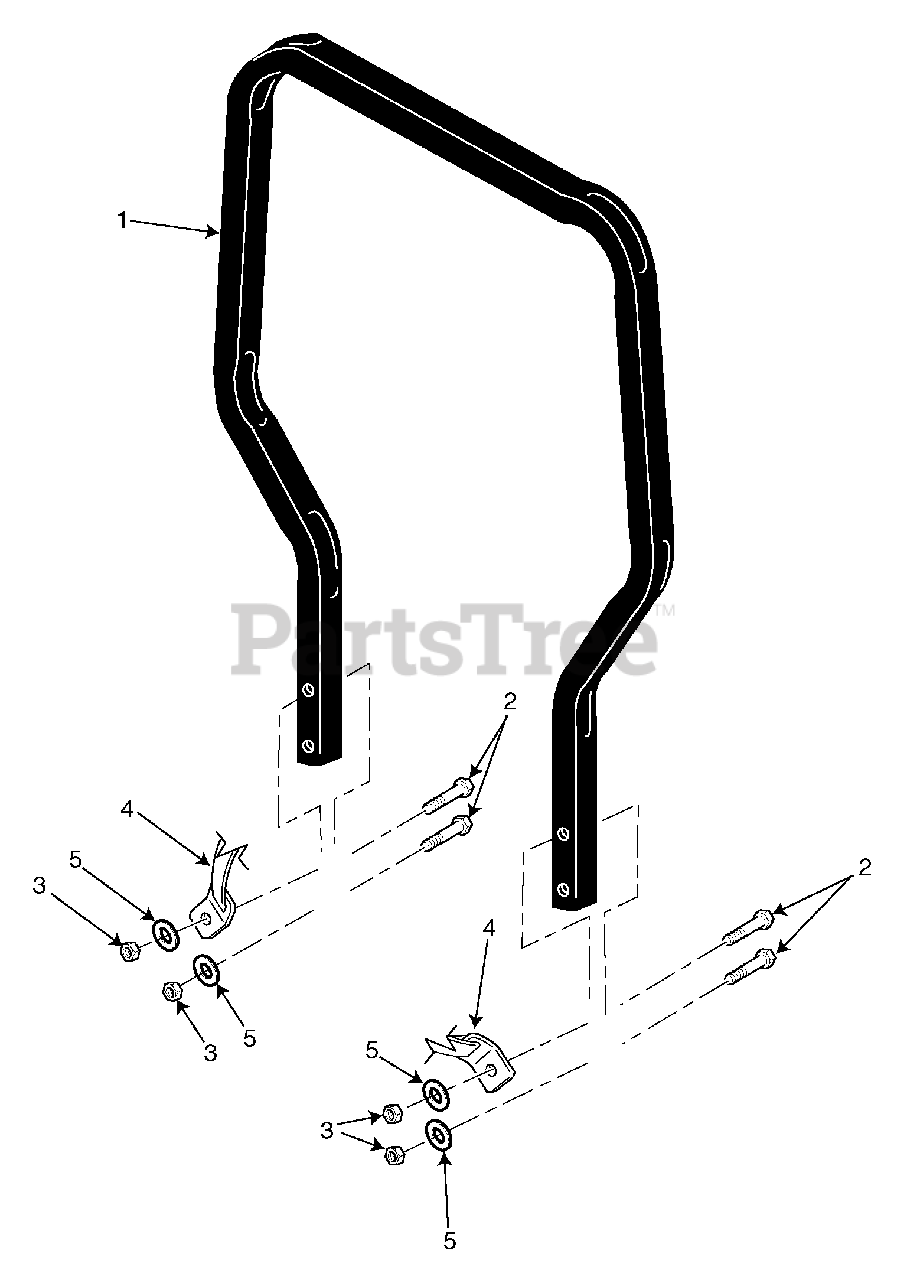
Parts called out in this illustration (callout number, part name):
1	STC ROPS
2	Bolt, Hex Head 1/2-13 x 3-1/2"
3	Nut, Center Lock 1/2-13
4	Seat Belt
5	Flatwasher, 1/2-.562 x 1.375 x .109
